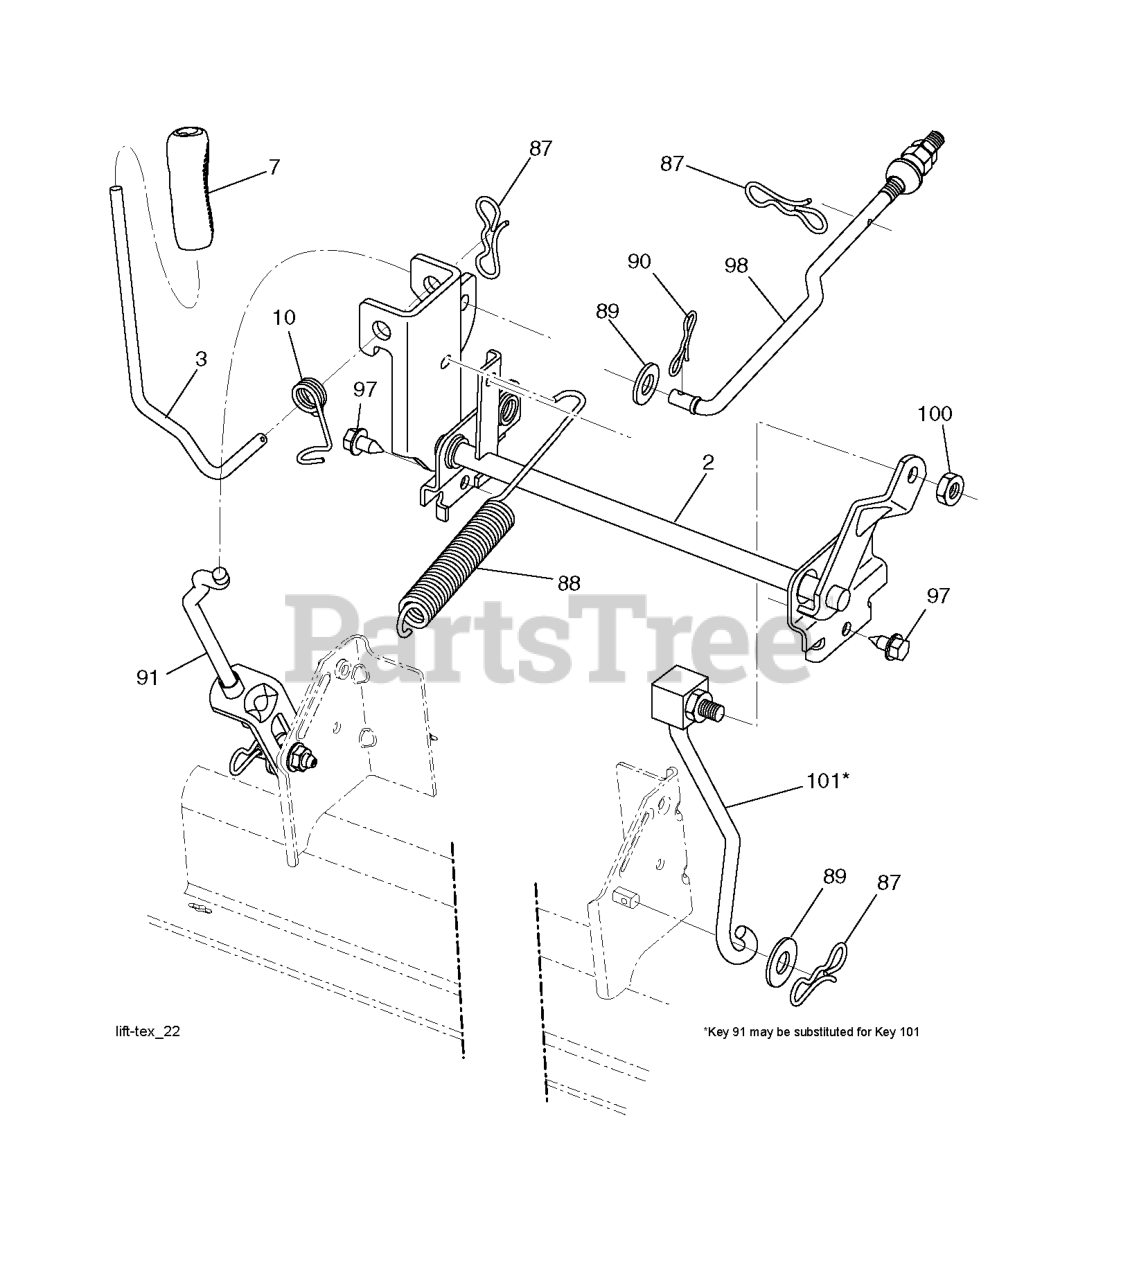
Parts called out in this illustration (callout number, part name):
2	SHAFT.ASM.CROSS.LIFT
3	LEVER.LIFT.HANDLE.LT
7	GRIP.HANDLE.LIFT.PVC.BLACK
10	SPRING.TORSION.LIFT.HANDLE
87	PIN.COTTER.7/16.BOW TI.
88	SPRING.LIFT.ASSIST
89	WASHER.CLEAR.ZINC
90	PIN.COTTER.5/16.BOW TI
91	LINK.ASM.LIFT.REAR
97	SCREW, 3/8-16X3/4
98	LINK.ASM.SUSP.FRONT.MW
100	LOCKNUT
101	LINK.ASM.LIFT.FIXE.38/42/46"
